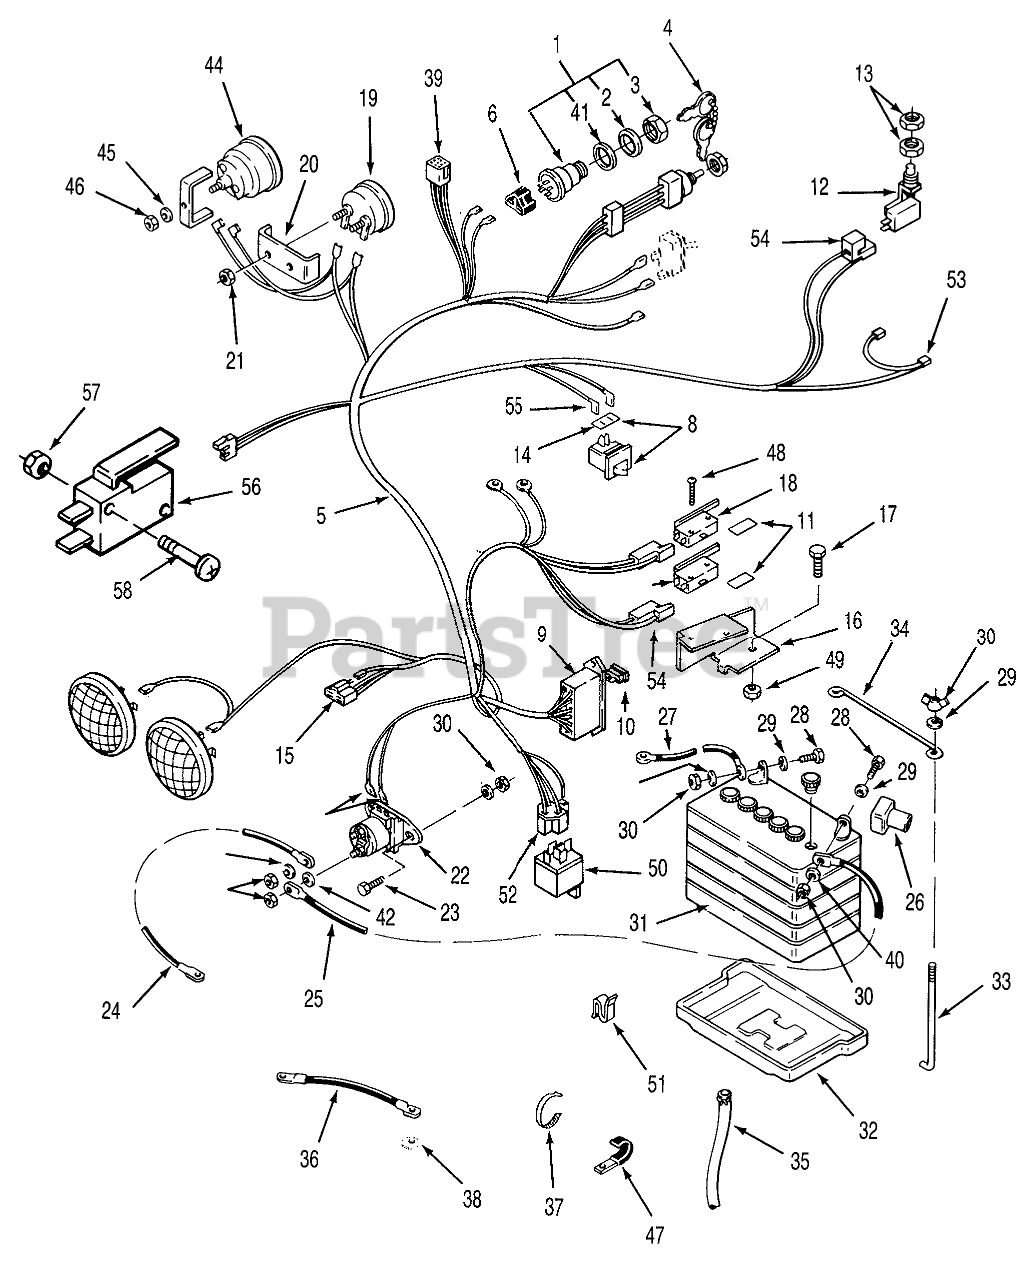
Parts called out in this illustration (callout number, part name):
1	Ignition Switch Ass-y
2	LOCKWASHER
4	Ignition Key
5	Wiring Harness Assembly 416-8
6	CONNECTOR BODY ELECT
7	TERMINAL 10
8	SWITCH INTERLOCK
9	FUSE-HOLDER 4 WAY
10	FUSE-BLADE, 15 AMP
11	BARRIER - SWITCH
12	Seat Switch
13	NUT-HEX, SPECIAL
14	SHIELD-DIRT SPST
15	5-CONTACT CONN BODY
16	BRACKET-SWITCH
17	Bolt
18	SWITCH
19	VOLTMETER
20	CLAMP MOUNTING
21	HEX NUT 10-32 E.S.
22	Solenoid
23	Screw
24	ASSY WIRE
25	CABLE-BLACK
26	Boot
27	ASSY WIRE
28	Bolt
30	Nut
31	Battery
32	TRAY-BATTERY
33	HOOK-BATTERY RETAIN
34	HOLDDOWN-BATTERY
35	TUBE-21" BATTERY DRAIN
36	WIRE GROUND
37	PLASTIC TIE
38	Washer-Lock
39	Terminal
40	Washer
41	Washer
42	Washer
43	Nut
44	GAUGE-HOURMETER
45	Lockwasher
46	Hex Nut
47	CLIP
48	Screw
49	NUT HEX 4-40 ELAST
50	RELAY
51	CLIP-CABLE
52	TERMINAL 10
53	Sur-Plug
54	CONNECTOR BODY
55	Terminal
56	SWITCH
57	E.S. Hex Nut No.4-40
58	Screw
